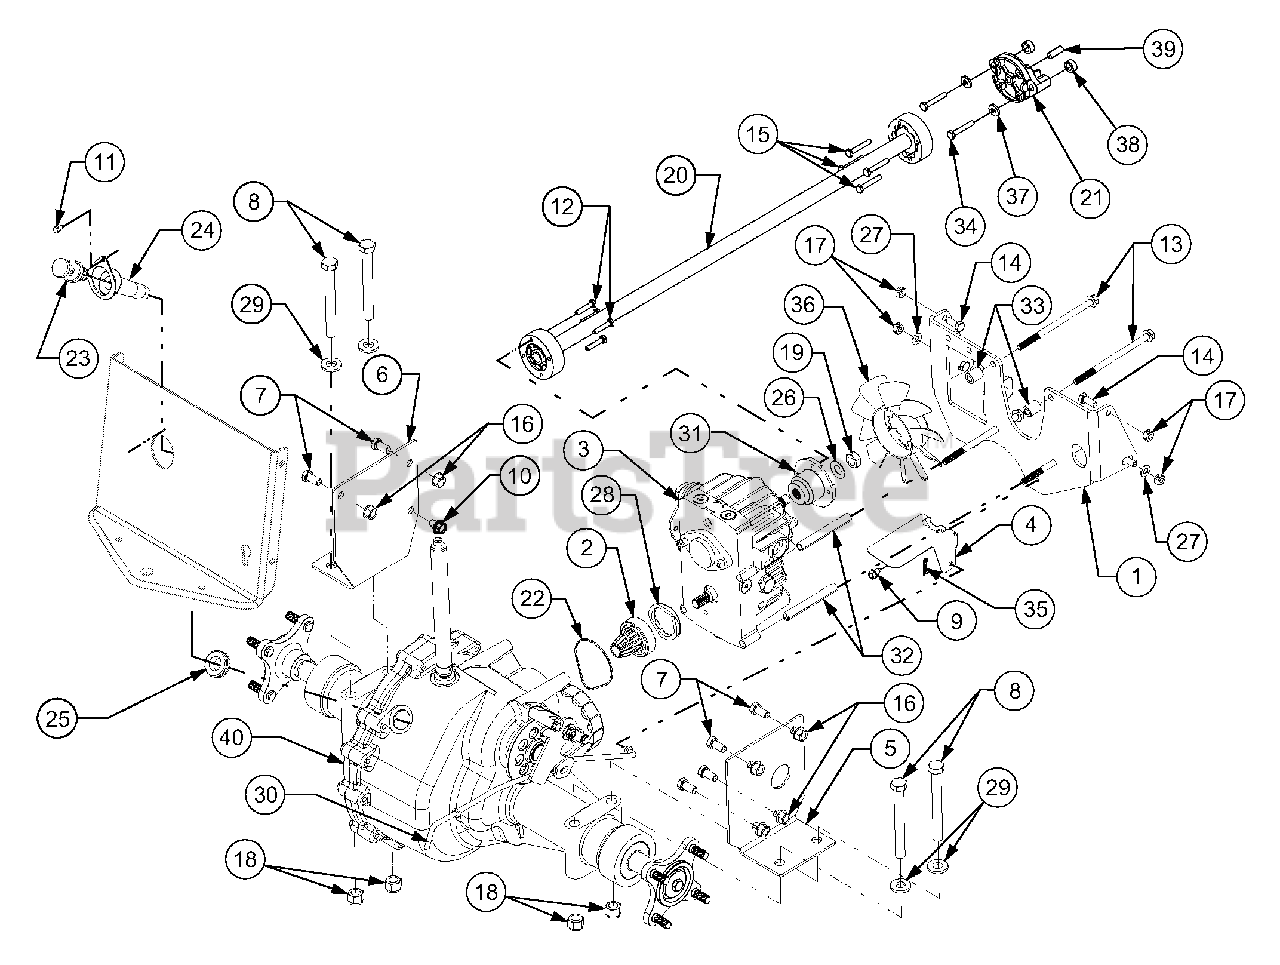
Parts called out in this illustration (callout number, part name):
1	Bracket, Torque
2	Gear Assembly, Pinion
3	Transmission, Hydrostatic
8	Screw, Hex Cap, 1/2-20 x 4.5 GR5
9	Scrw, Hx Wsh Hd Tapp, 1/4-20 x .5
10	Scrw, Hx Wsh Hd Tapp, 3/8-16 x .5
11	Scrw, Hx Wsh Hd Tapp, 10-16 x .44
12	Screw, Hex Patch, 1/4-20 x 1.25 GR5
13	Scrw, Hx Hd Tapp, 5/16-18 x 5.25
14	Screw, Hex Cap, 5/16-18 x .75 GR5
15	Screw, Hex Patch, 1/4-20 x 1.62 GR5
16	Nut, Hex Flange Lock, 3/8-16
17	Nut, Hex Cntr Lock, 3/8-16
18	Nut, Hex Nylon Lock, 1/2-20 GR2
19	Nut, Hex Top Lock Jam, 1/2-20
20	Shaft, Drive, 31.75 Lg
21	Adapter, Engine
22	Seal, Gland
23	Dipstick, Transmission
24	Holder, Dipstick
25	Grommet, Rubber, .75 x 1.063
26	Washer, Belleville
27	Washer, Flat, .344 x .688 x .065
28	Washer, Spring
29	Washer, Flat, .531 x 1.062 x .134
30	Rod, Hydro Dump Valve
31	Adapter, Hydro Pump
32	Spacer, Hydro, .323 x .443 3.51
33	Spacer, Hydro, .323 x .600 x .74
34	Screw, Hex Cap, 5/16-18 x 1.75 GR5
35	Internal Cotter Pin
36	Fan, Pump
37	Washer, Flat, .344 x .75 x .12
38	Spacer, .38 x .625 x .275
39	Pin, Locating, .352 Dia x 1.156
40	Transmission Assembly, Hydro - See "Hydro Transmission" for Parts Info.
